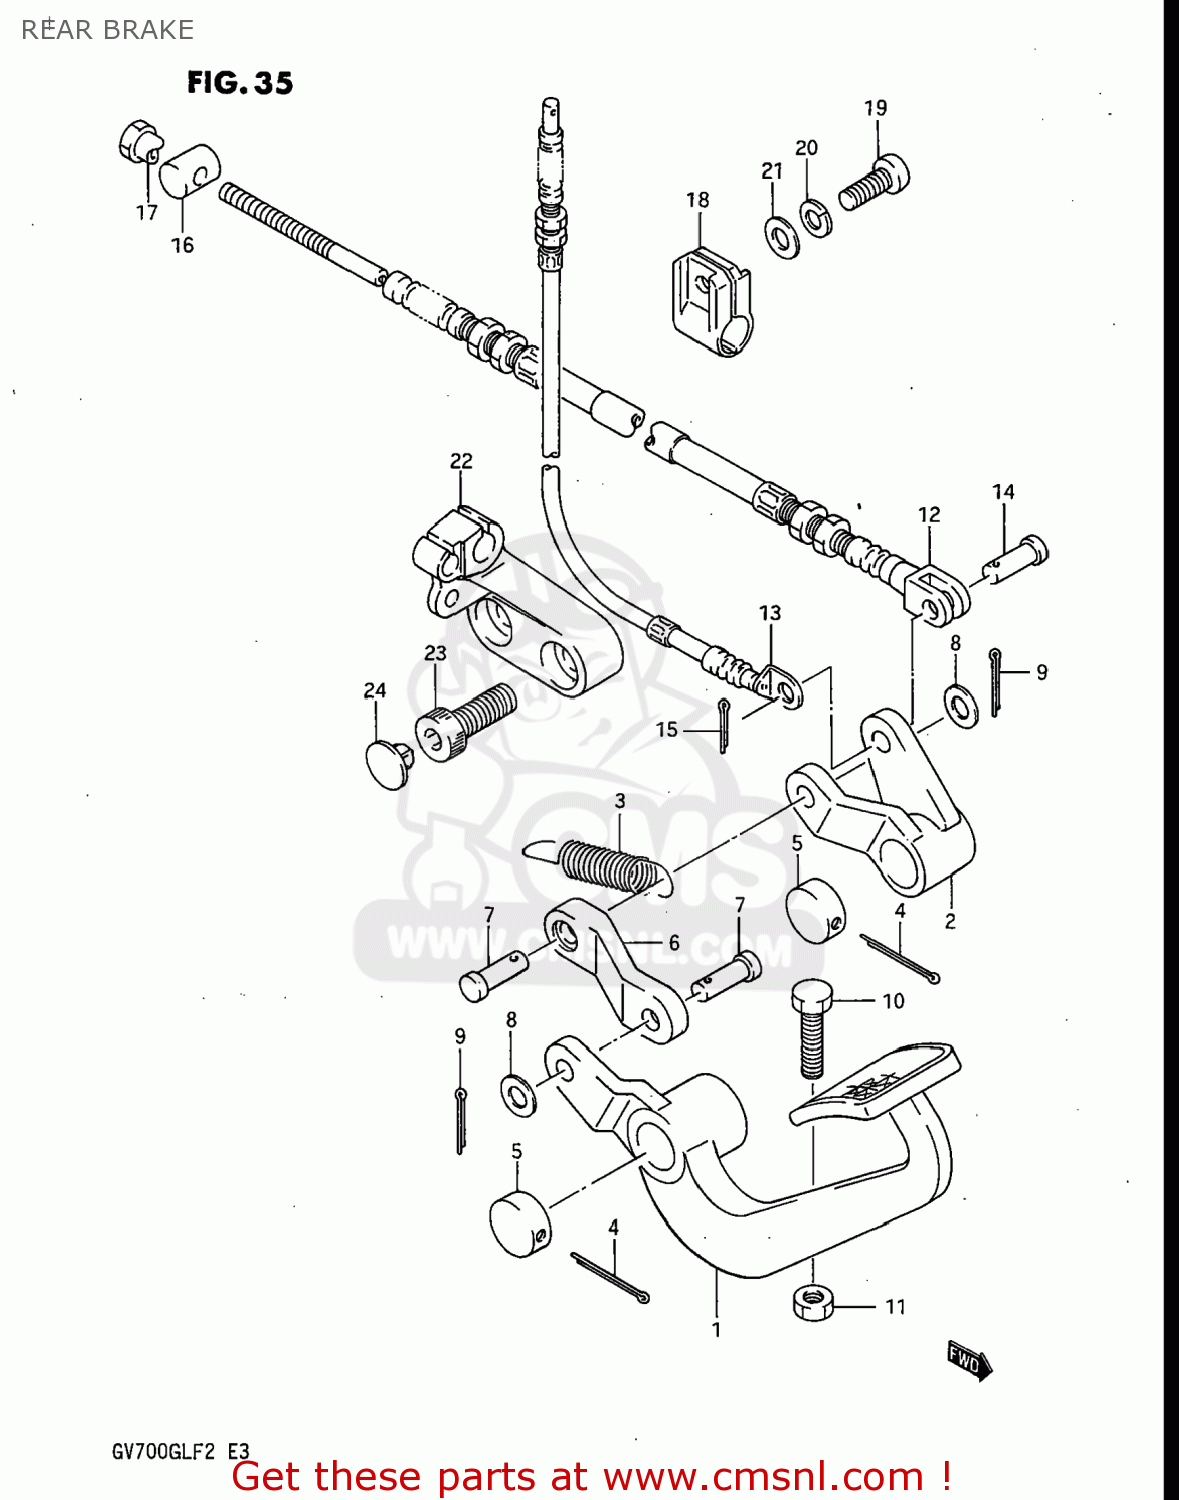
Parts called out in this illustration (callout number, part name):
1	PEDAL,BRAKE
2	ARM,BRAKE PEDAL
3	SPRING
4	COTTER PIN
5	CAP,BRAKE PEDAL
6	LINK,BRAKE PEDAL
7	PIN
8	WASHER (7.5X13X1)
9	PIN
10	BOLT(6X23)
11	NUT 6MM
12	CABLE ASSEMBLY,REAR BRAKE
13	CABLE ASSEMBLY,STOP LAMP SWITCH
14	PIN(L:17.5)
15	PIN
16	PIN
17	NUT (6MM)
18	CLAMP,BRAKE HOSE
19	SCREW
20	WASHER,LOCK
21	WASHER, LOWER
23	BOLT
24	CAP(OD:14.5)
